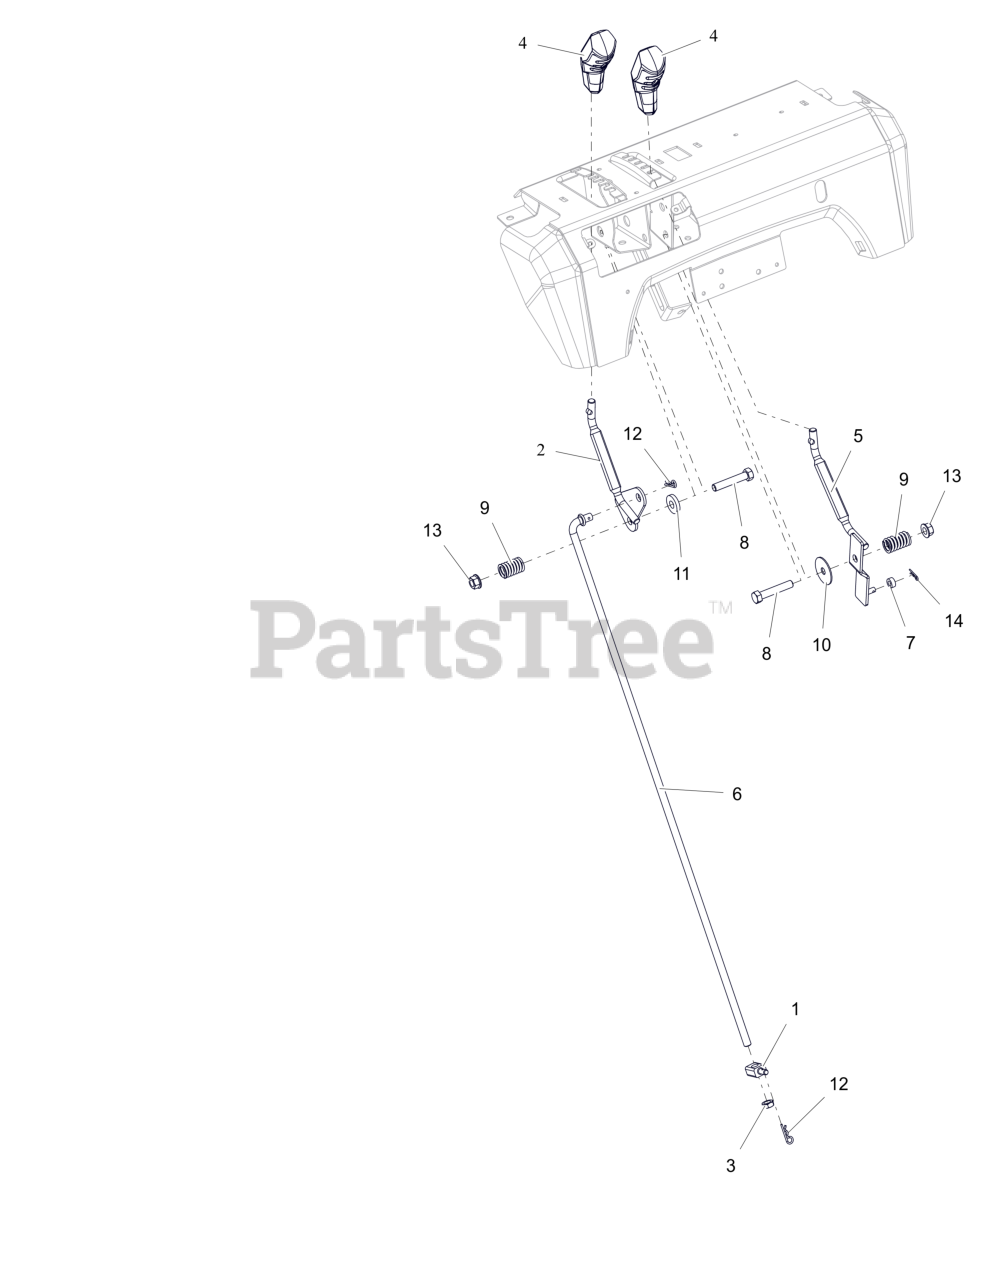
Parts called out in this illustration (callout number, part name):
1	PIVOT,SHIFT ROD .375-16(TRUNN)
2	WELDMENT,LG DASH SPEED CONTROL
3	NUT-JAM .375-16 G2 ZCC
4	KNOB, CONTROL
5	WELDMENT,LG DASH DEFL CONTROL
6	ROD, SHIFT - LARGE DASH DELUXE
7	BSHG-SLV .265X.500X.219
8	BLT,HEX .38-16X2.00 G5 ZCC
9	SG-COMP .125X.781X1.250
10	WSHR,FLT .380X1.50X.062 ZCC
11	WSHR, FLT .406X1.00X.188 ZCC
12	PIN, HAIR #213 .08X1.19 ZCC
13	NUT-LK-TOP-FLG .38-16 ZC120
14	PIN, HAIR #178 .06X.77 ZCC
